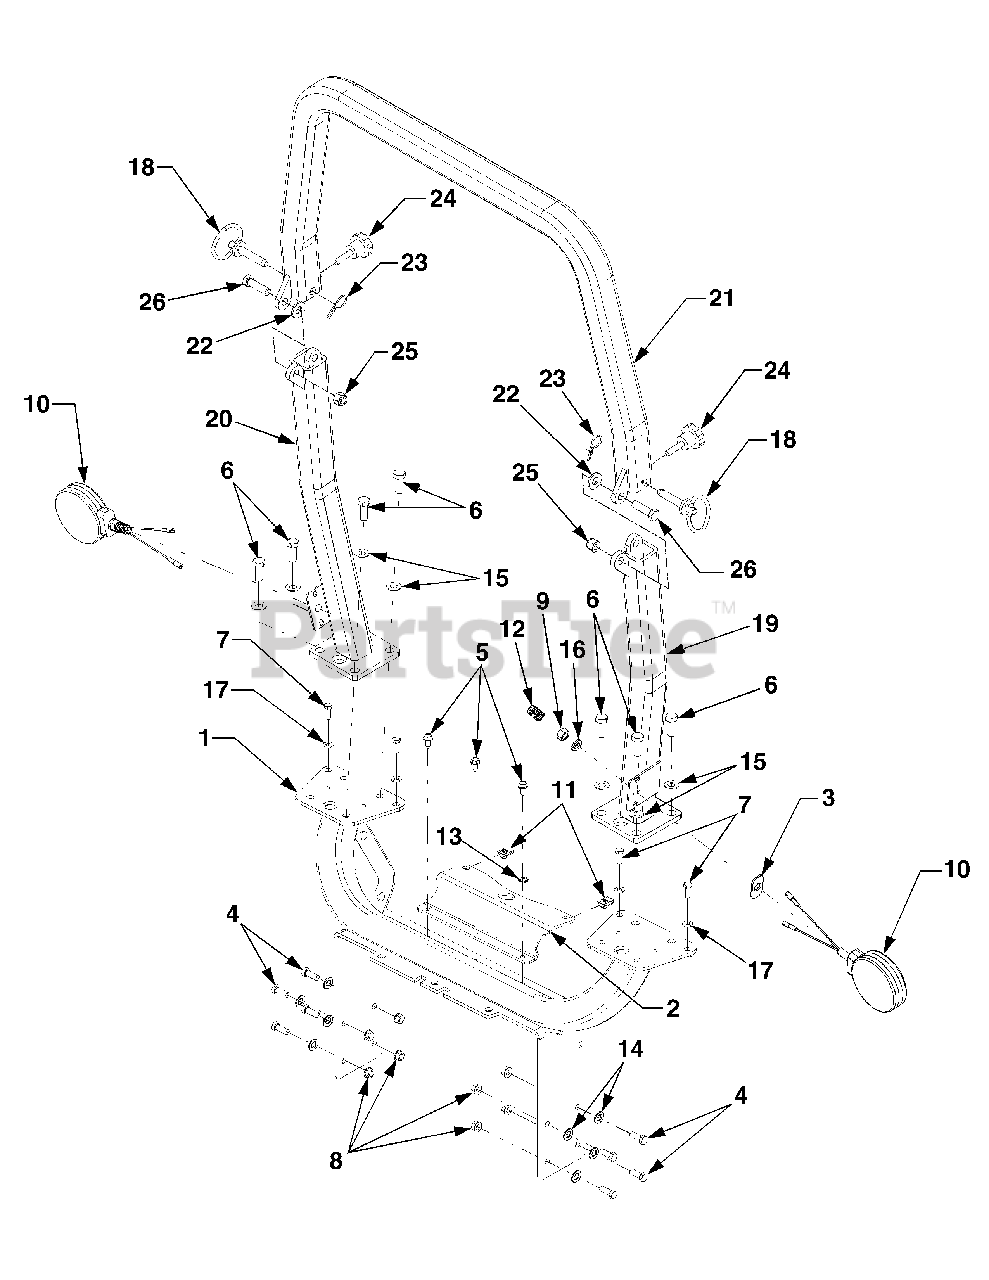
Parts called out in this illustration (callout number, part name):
1	Rops, Lower
2	Bracket, Rear Seat Mtg.
3	Plate, Spacer
4	Screw, Hex Cap, 3/8-16 x 1.0 GR5
5	Screw, Hex Wash. Hd. Tapp 5/16-18 x .75
6	Screw, Hex Cap, 1/2-13 x 1.25 GR5
7	Screw, Hex Cap, 5/16-18 x .875 GR5
8	Nut, Hx. Insert Flange Lck, 3/8-16 GRF
9	Nut, Hex, 1/2-20 GR5
10	Light, Hazard
11	Nut, Speed, 5/16-18
12	Conduit, 12 inch
13	Washer, Ext. Tooth Lock, 3/8
14	Washer, Flat, .375 x .74x.063
15	Washer, Flat, .51 x 1.0 x .060
16	Washer, Lock, 1/2
17	Washer, Flat, .345 x 1.0 x .10
19	Base, ROPS RH
20	Base, ROPS LH
22	Washer, Flat
23	Pin, Internal Cotter
24	Knob Assembly
25	Nut, Hex Insert Lock, 1/2-13
26	Screw, Hex Cap, 1/2-13 x 1.75 GR5
